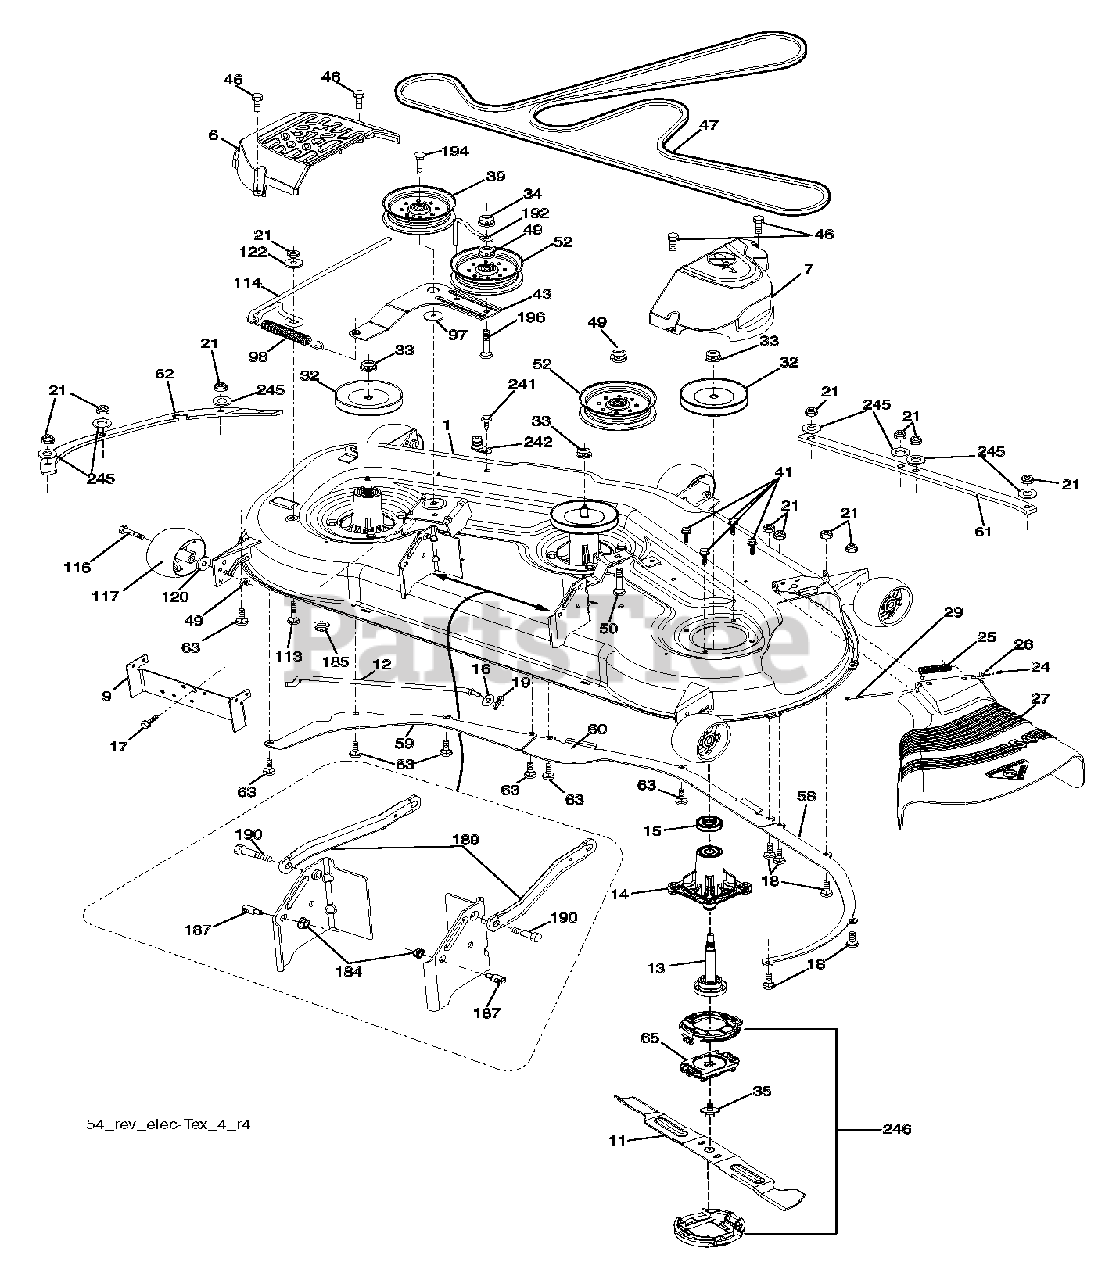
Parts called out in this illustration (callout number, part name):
1	DECK.SVC.54"
6	COVER.MANDREL.LH.54"20
7	COVER.MANDREL.RH.54.20
9	TORQUE STRAP PNT BLACK
11	Mower Blade, 54" Bagging
12	ROD.ANTI.SWAY.48/54"K4
14	Mandrel Housing, Rev Tall GRSBL
15	Extended Mandrel Bearing, Top
16	WASHER
17	SCREW
18	BOLT
19	PIN.COTTER.5/16.BOW TI
21	LOCKNUT
24	CAP-SLEEVE LT
25	SPRING, TORSION
26	NUT PUSH M
29	ROD.HINGE
32	PULLEY/MANDREL
33	NUT.FLANGE.LOCK.TOP
34	LOCKNUT
35	Screw, 7/16 X 20 X 1"
39	PULLEY.IDLER.4.50/HUB SPECIAL
41	Hex Washer Head Bolt, .313-18 X 1.19
43	ARM.IDLER
46	SCREW.1/4-20X5/8
47	Deck Drive Belt, 54"
49	NUT LOCK FLG 3/8-16 UNC
50	BOLT
52	PULLEY.IDLER.2006
58	BAFFLE.RIGHT.54"
59	BAFFLE.LEFT.54"
60	BAFFLE CENTER 54" MOWER
61	Front Bolt Reinforcement Plate, 54" X 431
62	Side Bolt Reinforcement Plate, 54" X 431
63	BOLT.CARRIAGE.5/16-18
65	Blade Holder, Revolution
98	SPRING, DECK DRIVE
113	BOLT CRT
114	ROD TENSION RELIEF
116	BOLT.SHOULDER.3/8-16X3-5/8.
117	WHEEL. GUAGE RALLY
122	BUSHING.RELIEF.TENSION
185	NUT.LOCK.FLANGE.7/16
187	STUD.FASTNER.W/ANTI-ROTATE
189	ARM.SUSPENSION.MOWER
190	BOLT.SHOULDER
192	KEEPER.BELT.IDLER.54"T
194	BOLT.HEX.WASHER.HEAD.7/16-24X
196	BOLT
241	SCREW.TT.#10-32X.5.3/8.FLANGE
242	PORT.WASHOUT
245	WASHER
246	Revolution Assembly Cap, Upper
